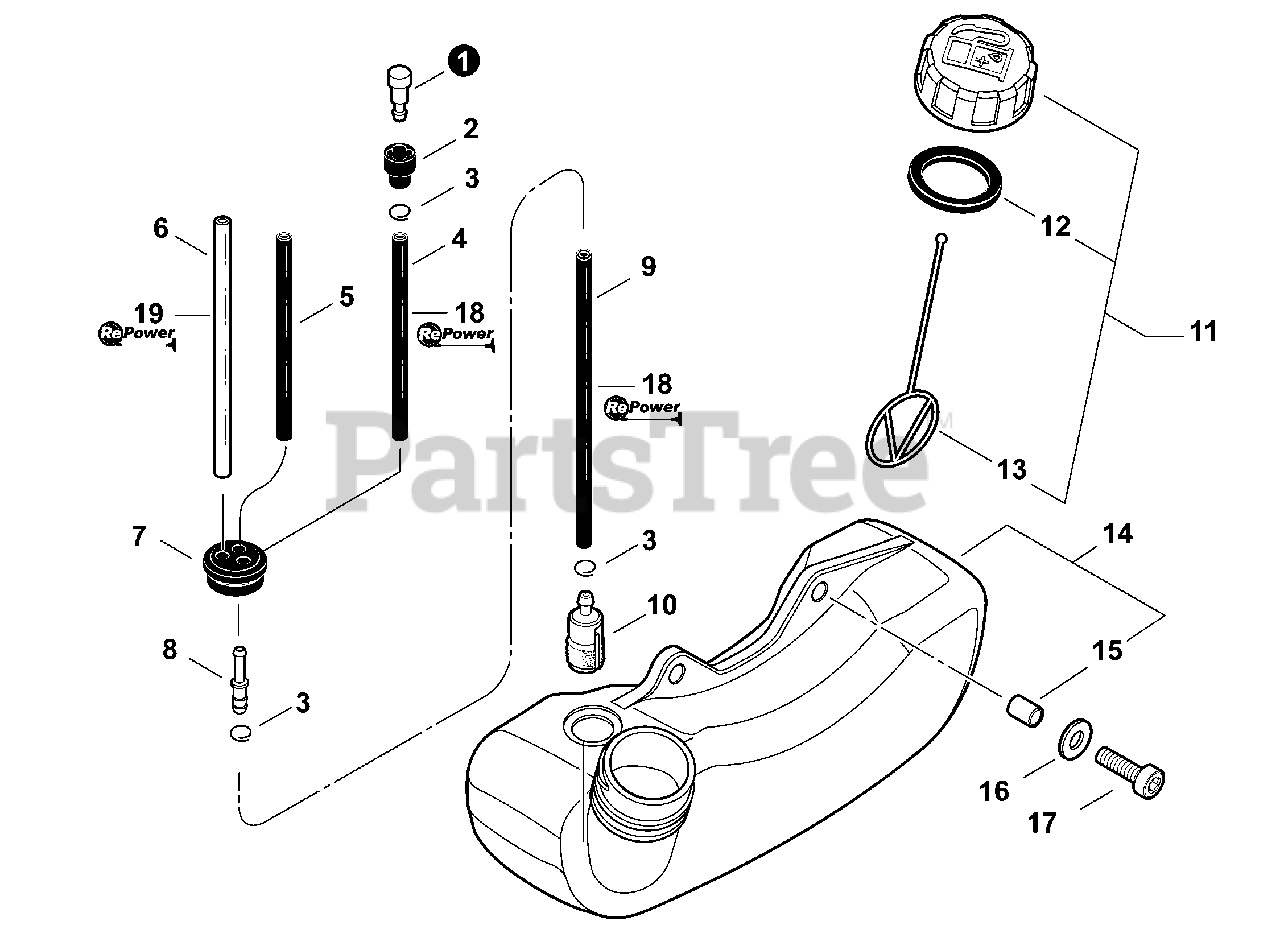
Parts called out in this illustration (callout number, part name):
1	VENT ASSY
2	HOLDER, VENT
4	PIPE, FUEL 3×5×70 BLACK
5	PIPE, FUEL 3×5×87
6	PIPE, FUEL RETURN 3×6×90mm
7	GROMMET, FUEL 5
8	CONNECTOR, PIPE 5×3.5
9	PIPE, FUEL 3×5×130 BLACK
10	FILTER, FUEL
11	CAP ASSY, FUEL
12	GASKET, FUEL CAP
13	CONNECTOR, CAP L= 100mm
14	TANK ASSY, FUEL
15	SPACER 6.2×7.8×6
16	WASHER 5.5×12×0.8
17	BOLT 5×16
18	PIPE, BULK - REPOWER 3×5mm BLACK
19	PIPE, BULK - REPOWER 3×6mm CLEAR
